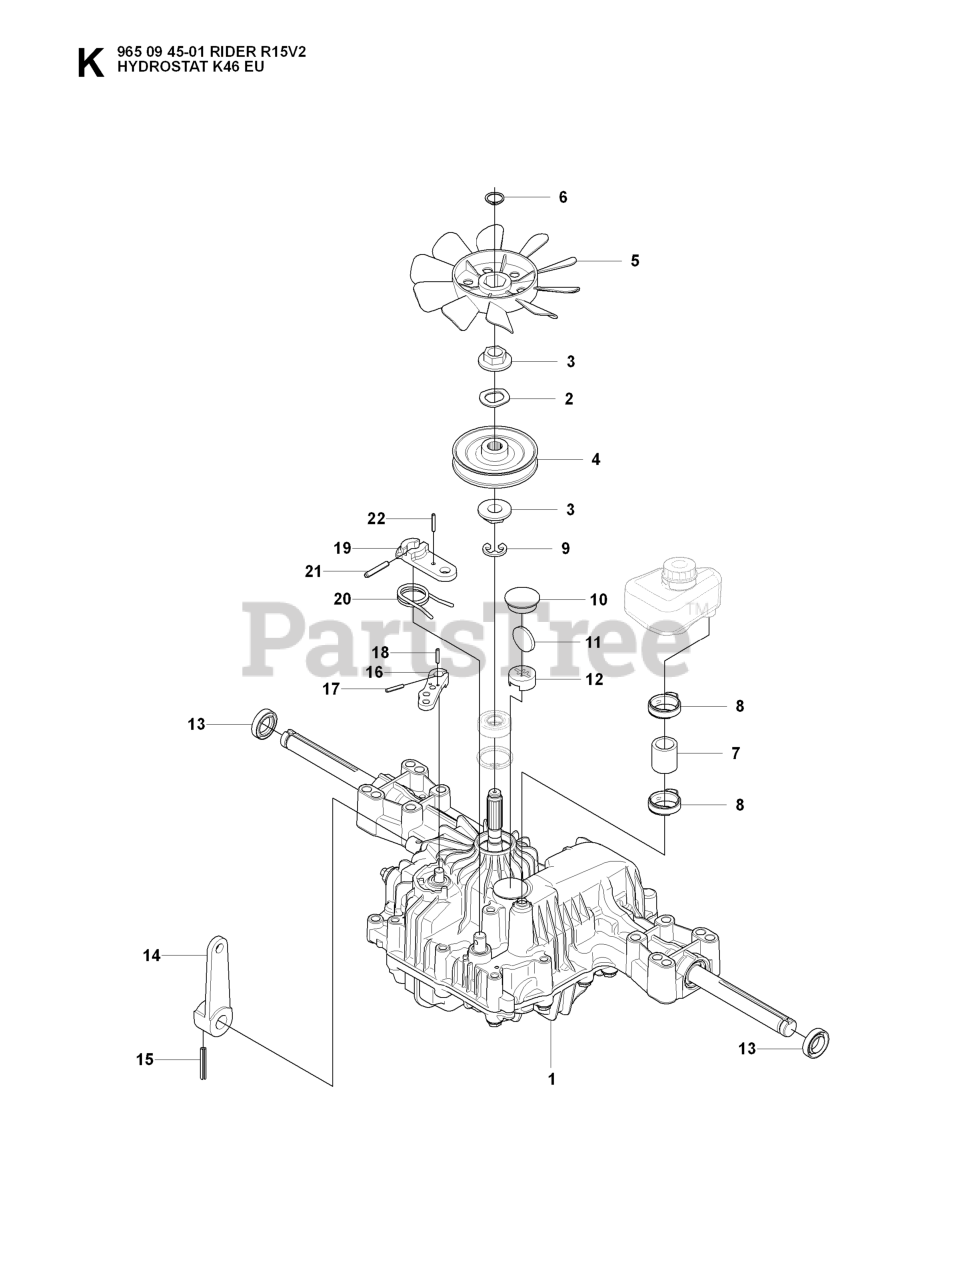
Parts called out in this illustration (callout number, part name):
1	HYDROSTAT 7A646024070
4	PULLEY - 3 1/2"
5	FAN.BLACK.1A646083070
6	RETAINING RING **
7	PIPE
8	CLAMP
9	Retaining Ring
13	RP SEAL.19, 19216334280
20	RETURN SPRING
